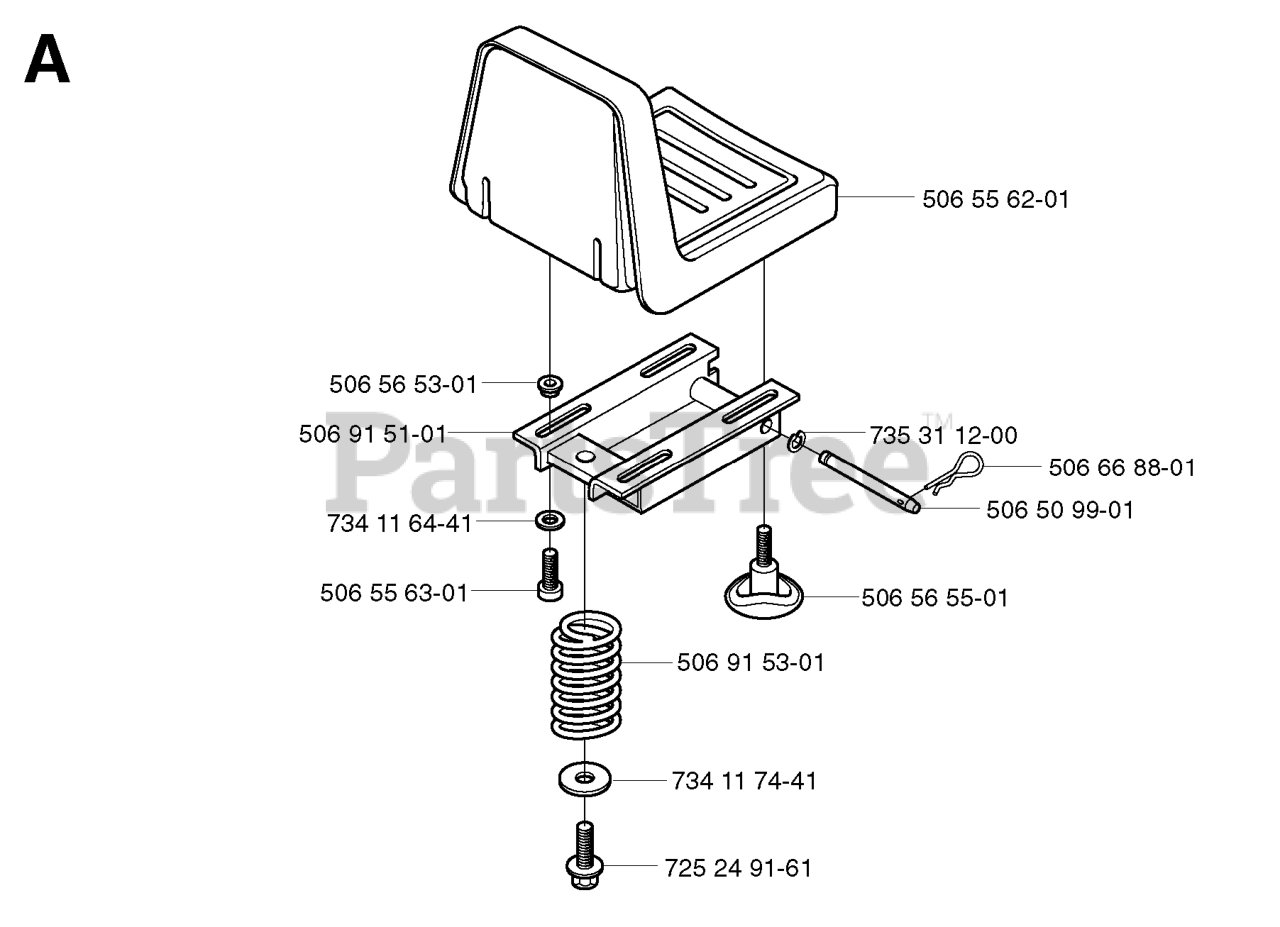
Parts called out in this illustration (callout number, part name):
2	SPRING,BRAKE RETURN
3	PULLEY TRANS
4	RETAINING RING LT
5	STRAP TORQUE
6	SCREW 5/16"
8	ROD SHIFT FENDER ADJUST STLT
10	PIN COTTER
11	WASH-SHFT PLT LT
13	BOLT 1/4-28X3/4
14	LOCKWASHER
16	NUT.71038.31-18.HEX.NYLOCK
19	NUT
21	KNOB.DUCKHEAD.1/2
24	NUT
25	SPRING ROD LT
26	WASHER
27	COTTER PIN
28	ROD BRAKE PARK LT
29	PLUNGER CAP
30	BRACKET TRANSAXLE
31	KEEPER BELT LH
32	BOLT
34	SHAFT, FOOT PEDAL
35	BEARING.NYLON
37	DRIVE PIN
38	FLAT IDLER PULLEY
41	KEEPER.BELT.IDLER.FLAT
42	WASHER
47	IDLER PULLEY
48	BELLCRANK, CLUTCH
49	RETAIN BELT
50	BOLT
52	LOCKNUT
53	LINK, CLUTCH LT
55	SPRING, RETURN LT
57	V-BELT
59	KEEPER, BELT CENTER
61	SCREW 3/8-16X3/4
62	PEDAL COVER T
63	PULLEY.ENG.CL.MECH.SLVR.LT/YT
64	BOLT
65	LOCKWASHER
66	KEEPER BELT ENGINE
70	KEEPER BELT ENG
72	WASHER
74	SPACER AXLE
77	SQUARE KEY
79	KEY STD (1373) DANA
81	SHAFT ASM CROSS TAPERED
82	SHIFT SPRING
83	WASHER
84	LINK.TRNSAXLE
85	NUT LOCK CENTER 1/4 -28 FNTHD
90	NUT.PUSH.3/16
96	RETAINER M
113	STRAP TORQUE LH LT
116	BOLT
150	BUSHING.BELLCRANK.GRD.DR
151	WASHER 12/32X2X10GA
156	WASHER.SRRTD.5/16
158	BRACKET
159	HUB
161	BOLT
162	NUT.CROWNLOCK.1/4
164	Washer 5/8 x .281 x 10 Ga.
165	RP BRACKET
168	BOLT.SHOULDER.5/16-18X
169	PLATE.FASTENING.CROSS.SHAFT
197	NYLINER SNAP 5/8" ID
198	WASHER.NYL.7/8IDX.105"HYD CR
202	BOLT.3/8-16X1.50
